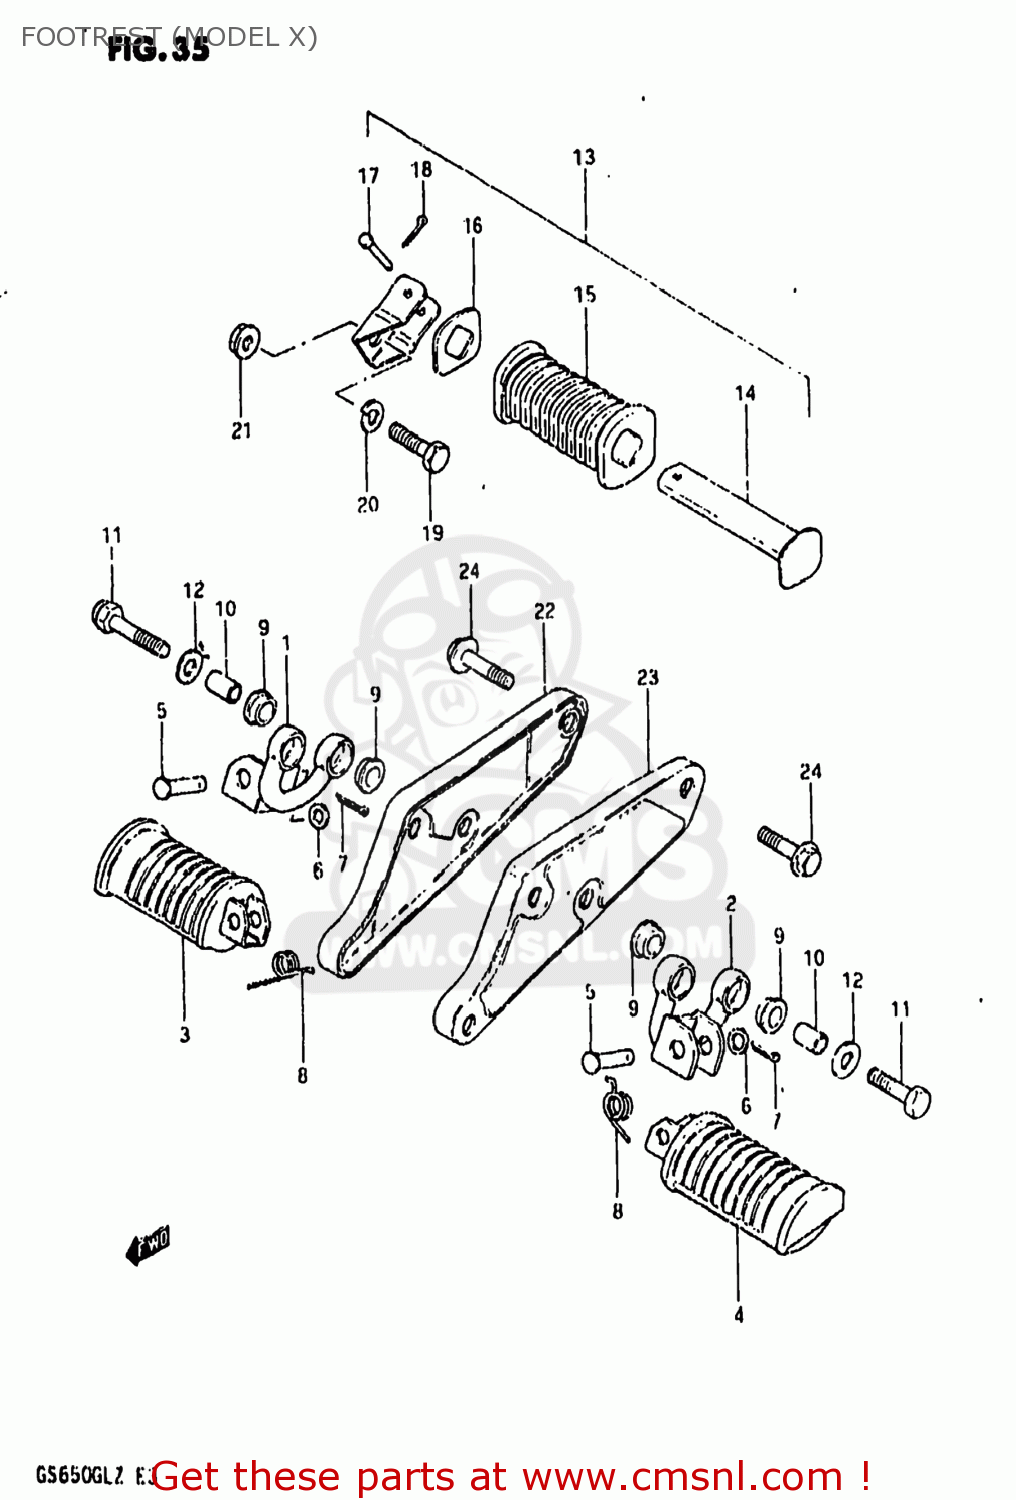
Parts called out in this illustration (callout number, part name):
1	BAR,FRONT FOOTREST
2	BAR,FRONT FOOTREST,LEFT
3	RUBBER,PILLION FOOTREST,R
4	RUBBER,PILLION FOOTREST,L
5	PIN
6	WASHER
7	PIN
8	SPRING
9	BUSH
10	SPACER (10.2X14X20)
11	BOLT
12	WASHER(10.5X28X2.3)
13	FOOTREST ASSY,PILLION,R
14	BAR,REAR FOOTREST,LEFT
15	RUBBER,PILLION FOOTREST
16	WASHER,FOOTREST RUBBER
17	PIN
18	PIN
19	BOLT,M10X1.25X
20	LOCK WASHER
21	NUT
22	BRACKET
23	BRACKET
24	BOLT
